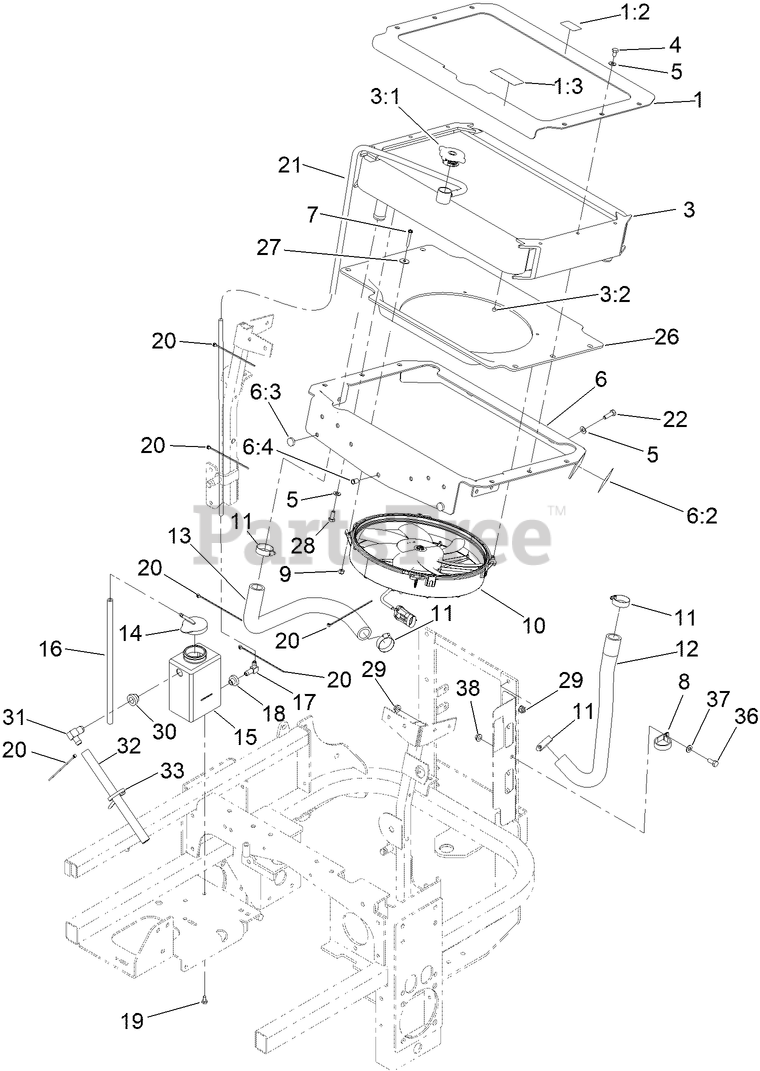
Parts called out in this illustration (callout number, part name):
1	TOP RADIATOR PLATE ASM
1:2	DECAL-WARNING
1:3	DECAL-ANTIFREEZE
3	RADIATOR ASM
3:1	CAP-RADIATOR
3:2	PLUG-PIPE
4	SCREW-HH
5	WASHER-PLAIN
6	BOTTOM RAD PLATE ASM
6:2	DECAL-DANGER
6:3	NUT-CLINCH
6:4	BUMPER
8	CLIP-LOOM
9	NUT-LOCK, HH
10	FAN-HI PERFORMANCE
11	CLAMP-HOSE
12	HOSE-RADIATOR, LH
13	HOSE-RADIATOR, RH
14	CAP-TANK, OVERFLOW
15	TANK-OVERFLOW
16	HOSE-LINE, FUEL
17	FITTING-ELBOW, 90 DEG
19	SCREW-HH
20	TIE-CABLE
21	HOSE-OVERFLOW
22	SCREW-HH
26	SHROUD
27	WASHER
28	SCREW-HH
29	NUT-HF
31	FITTING-ELBOW
32	HOSE-OVERFLOW
33	TIE-CABLE
36	SCREW-HH
37	WASHER-FLAT
38	NUT-HF
